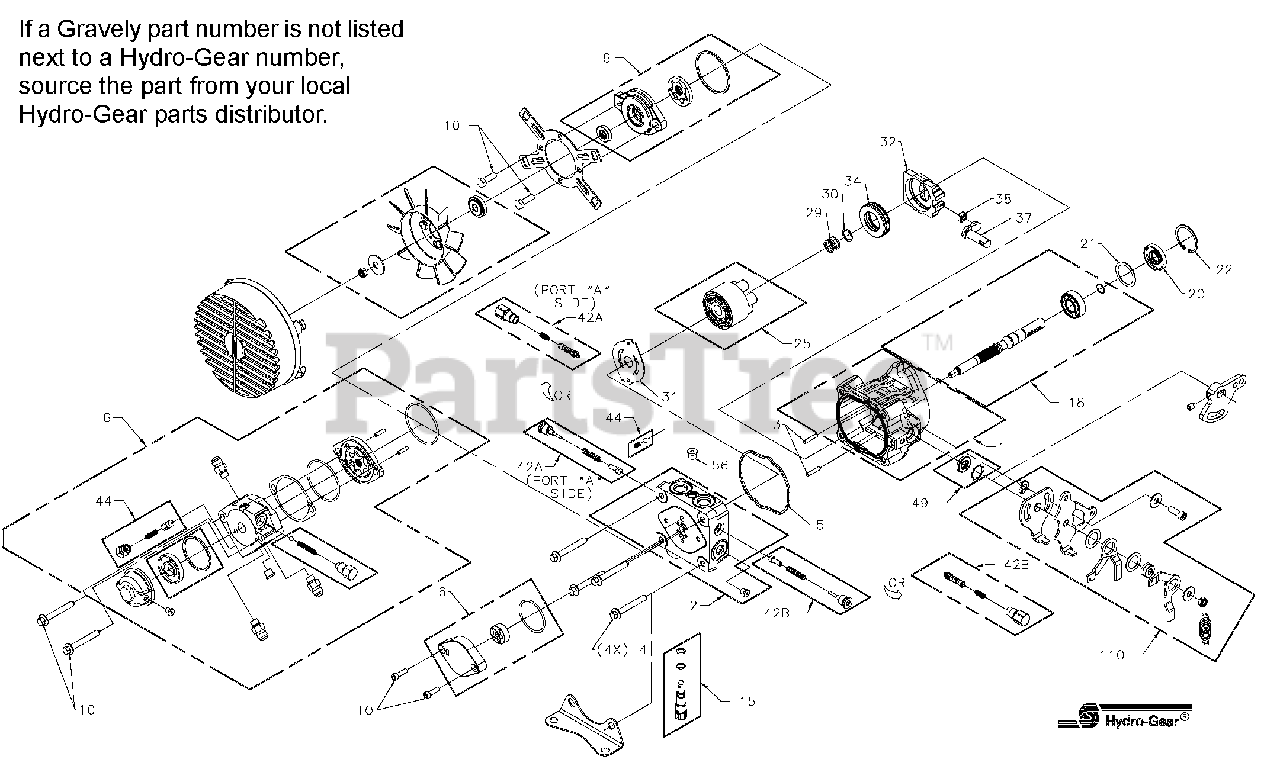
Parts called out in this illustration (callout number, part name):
1	Kit, Housing
2	Kit, End Cap w/Poppets
3	Straight Headless Pin
4	Hex, Flange Bolt M8-1.25 x 60mm
6	Kit, Chg Pump
10	Cap Screw 5/16-18
15	Kit, Bypass
18	Kit, Pump Shaft (15mm Straight Keyed, Thru)
20	Lip Seal 17 x 40 x 7 PTC
21	Spacer
22	Retaining Ring
25	Cylinder Block Kit
29	Block Spring
30	Block Thrust Washer
31	Valve Plate
32	Swashplate
34	Ball Thrust Bearing
37	Arm, Trunnion, Tapered Square
38	Slot Guide
42	Kit, Shock Valve (200 Bar .031 Orifice)
44	Kit, Charge Relief Valve
49	Trunnion Seal - Retainer Kit
56	Plug, Straight Thread
110	Kit, Return
NS	Overhaul Seal Kit
